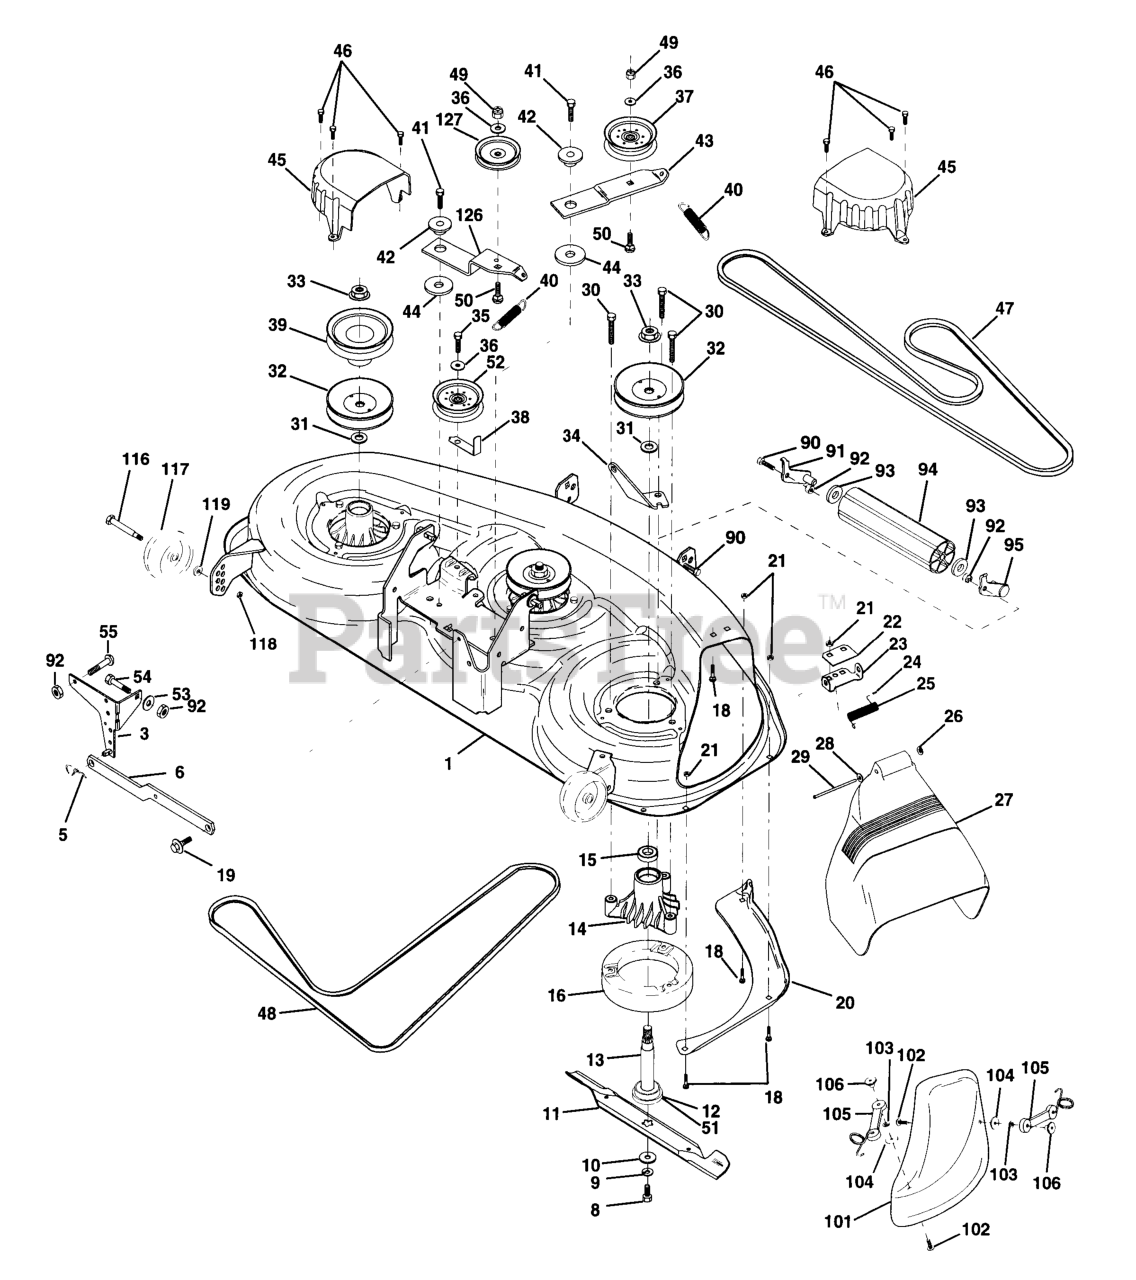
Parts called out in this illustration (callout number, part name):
1	HOUSING MOWER
3	BRACKET SWAY BAR
5	RETAINER-SPRNG RB
6	REAR SUSP ARM
8	BLADE BOLT
9	LOCKWASHER
10	WASHER.BLADE
11	MULCH BLADE 46"
12	BEARING.BALL.#6204.(MANDREL)
13	SHAFT.ASM.W/BEARING
14	HOUSING.MANDREL.44/46" VENT
16	STRIPPER
18	BOLT
19	BOLT SHD 5/16-18
20	BAFFLE, VORTEX MOWER 46"
21	LOCKNUT
22	STIFFENER BRACKET
23	DEFLECTOR BRACKET
24	CAP-SLEEVE LT
25	SPRING TORSION
26	NUT PUSH M
27	SHIELD, DEFLECTOR MOWER
28	Washer 11/32 x 5/8 x 16 Ga.
29	ROD.HINGE
30	SCREW
31	WASHER
32	PULLEY, MANDREL
33	NUT
34	ANCHOR, SPRING DECK 46"
35	SCREW LT
36	WASHER
37	FLAT IDLER PULLEY
38	KEEPER
39	PULLEY.DRIVEN.DECK.46"
40	SPRING.SEC.44"VEN
41	SCREW
42	SPACER RETAINER
43	ARM IDLER DECK 46"
44	HARDENED WASHER
45	COVER MANDREL 46
46	SCREW.1/4-20X5/8
47	BELT V SECONDARY
48	V-BELT PRIMARY 50"
50	BOLT.3/8-16X1.50
51	WASHER FELT
52	PULLEY IDLER FLAT 46 PRI DRIVE
53	WASHER
54	BOLT
55	BOLT D
90	BOLT
91	BRACKET LH (A)
92	NUT
93	Washer 17/32 x 7/8 x 16 Ga.
94	NOSE ROLLER
95	BRACKET RH (B)
101	COVER.MULCH.46"3-BLADE.(2 2)
102	SCREW
103	LOCKWASHER #10
105	LATCH ASSEMBLY
106	WELDNUT
116	BOLT, SHOULDER
117	WHEEL GAGE DONUT
118	LOCKNUT
119	WASHER.5/16.FLAT.STE.STD.
126	ARM IDLER PRIM 46
127	PULLEY.IDLER.4.25
